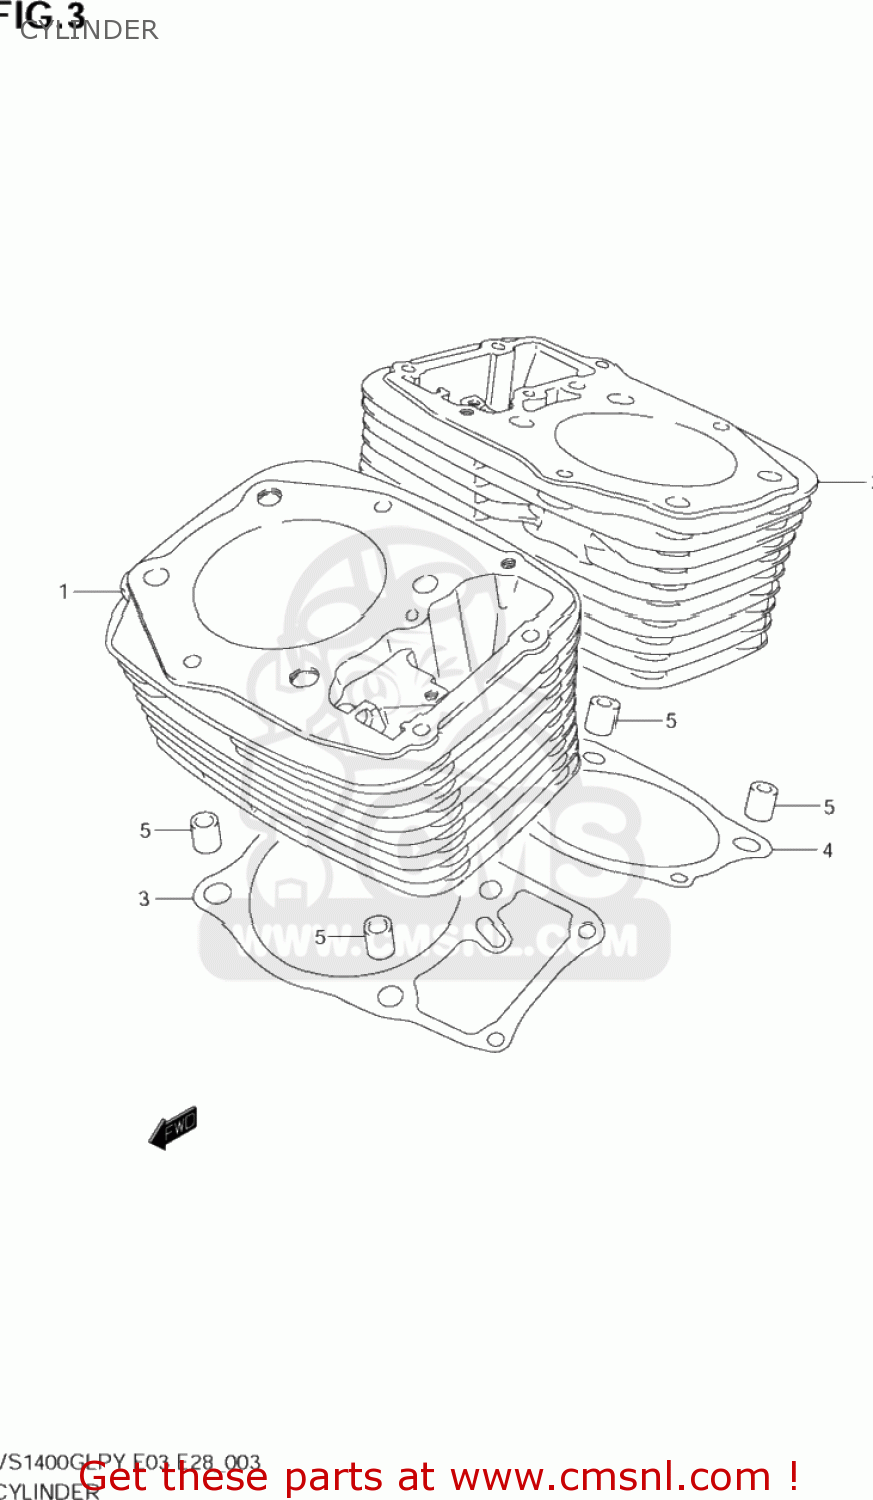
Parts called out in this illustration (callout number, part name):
1	CYLINDER,FRONT
2	CYLINDER,REAR
3	GASKET,CYLINDER FR (NAS)
4	GASKET,CYLINDER RR (NAS)
5	PIN
